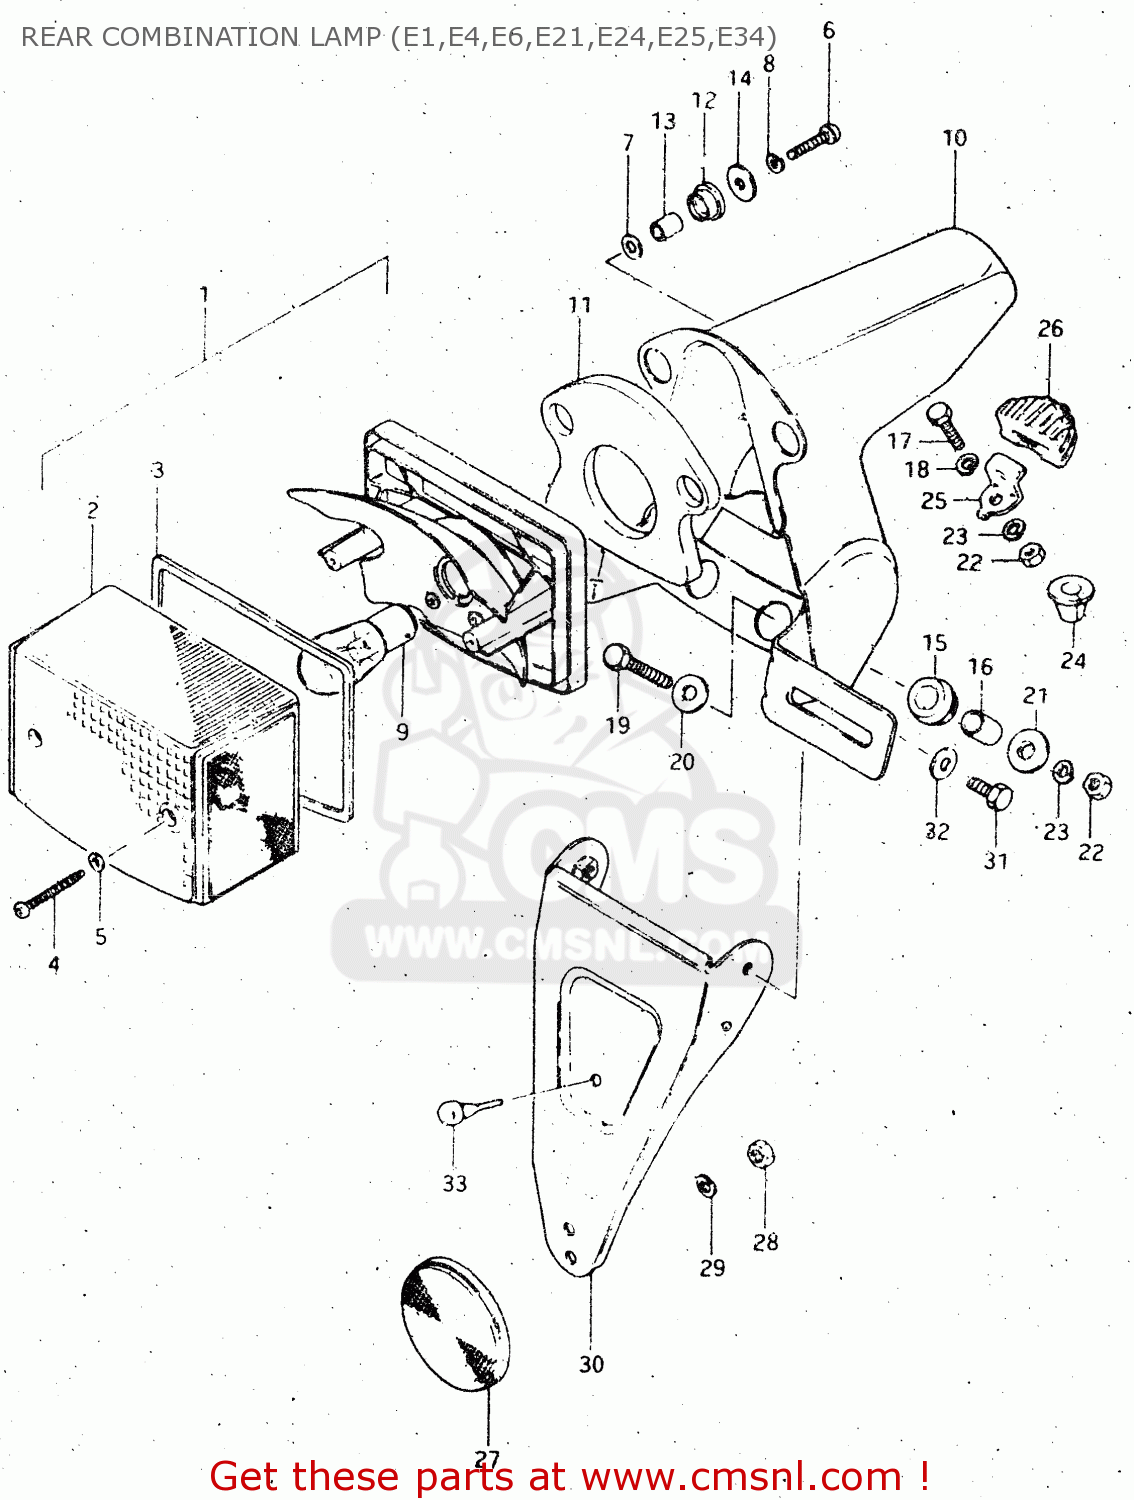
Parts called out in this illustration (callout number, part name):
1	LAMP UNIT, TAIL
2	LENS,RR COMBINATION
3	GASKET (NAS)
4	SCREW
5	GASKET (NAS)
6	SCREW
7	WASHER
8	LOCK WASHER
9	BULB (6V,21/5W)
10	BRACKET ASSY
11	CUSHION,REAR COMBINATION LAMP
12	CUSHION,REAR COMBINATION LAMP
13	SPACER,REAR COMBINATION LAMP
14	WASHER,REAR COMBINATION LAMP
15	CUSHION,REAR COMBINATION LAMP
16	SPACER
17	BOLT
18	LOCK WASHER
19	BOLT
20	WASHER (6.5X20X1.2)
21	WASHER
22	NUT
23	WASHER, LOWER
24	GROMMET
25	PLATE,RR COMBINATION LAMP
26	CUSHION,REAR COMBINATION LAMP
27	REFLEX REFLECTOR,RR
28	NUT
29	LOCK WASHER
30	BRACKET
31	BOLT
32	WASHER
33	CUSHION
